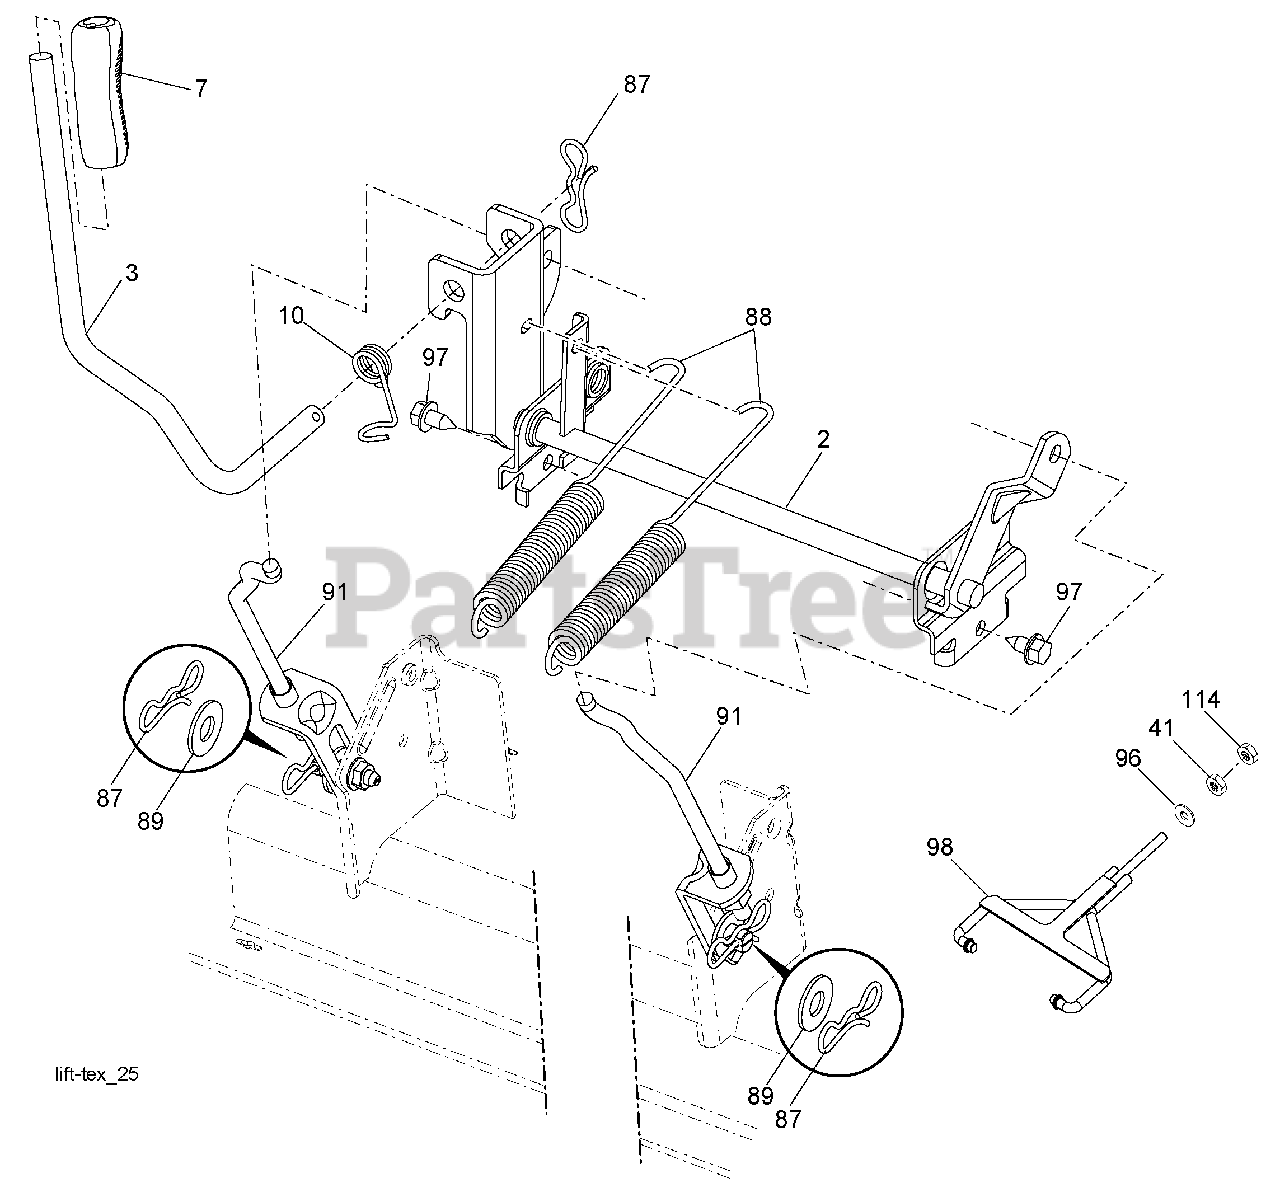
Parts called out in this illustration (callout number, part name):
2	Shaft Asm., Lift
3	Lever Asm., Lift RH
7	Grip, Lever
10	Spring Torsion
41	Nut lift Link 7/16-20
87	Pin Cotter 7/16 Bow Tie Lock
88	Spring Lift Assist
89	Washer Clear Zinc
91	Link Lift Susp Mower Rear
96	Bushing Spherical
97	Screw 3/8-16 x 3/4
98	Link Lift Front Deck Susp
114	Nut Hex Jam 7/16-20
